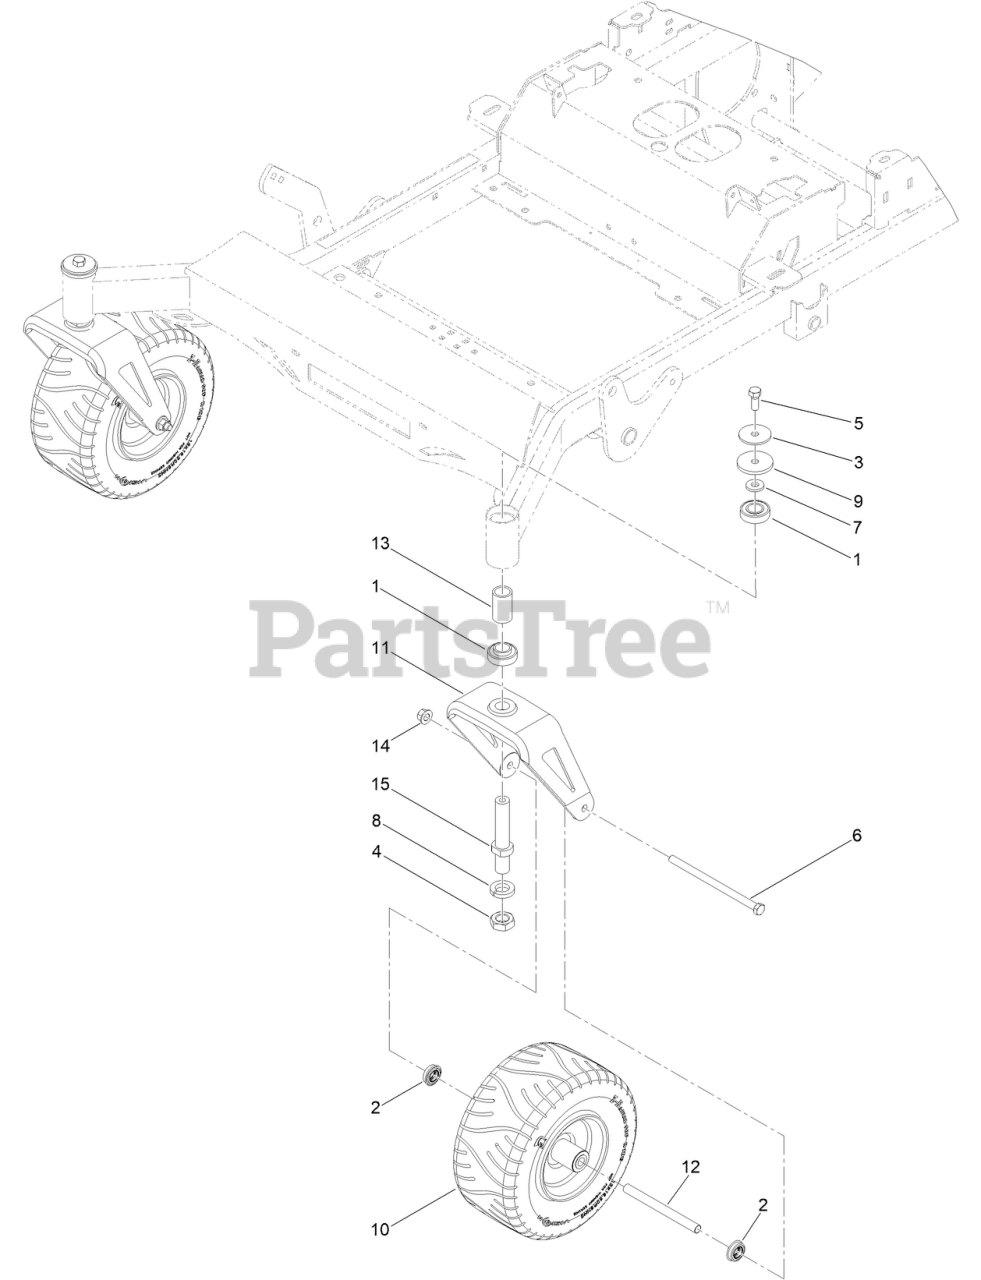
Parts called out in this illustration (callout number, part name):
1	BEARING-BALL
2	RZ FT WHEEL BEARING
3	MWR CASTER SHAFT WASHER
5	1/2-20 X 1-1/4 HEX FLANGE BOLT GR 8 YZ
6	SCREW-HH
7	1/2 FENDER WASHER 1-1/4IN OD ZINC
8	1IN L/W MED SPLIT ZC
9	FT HUB PLASTIC WASHER
10	SPARTAN RADIAL FT TIRE AND WHEEL ASSM
11	RT AND SRT CASTER WHEEL FORK
12	MWR FT WHEEL SPANNER
13	CASTER FORK SHAFT BEARING SPACER
14	NUT-LOCK
15	MWR CASTER SHAFT
